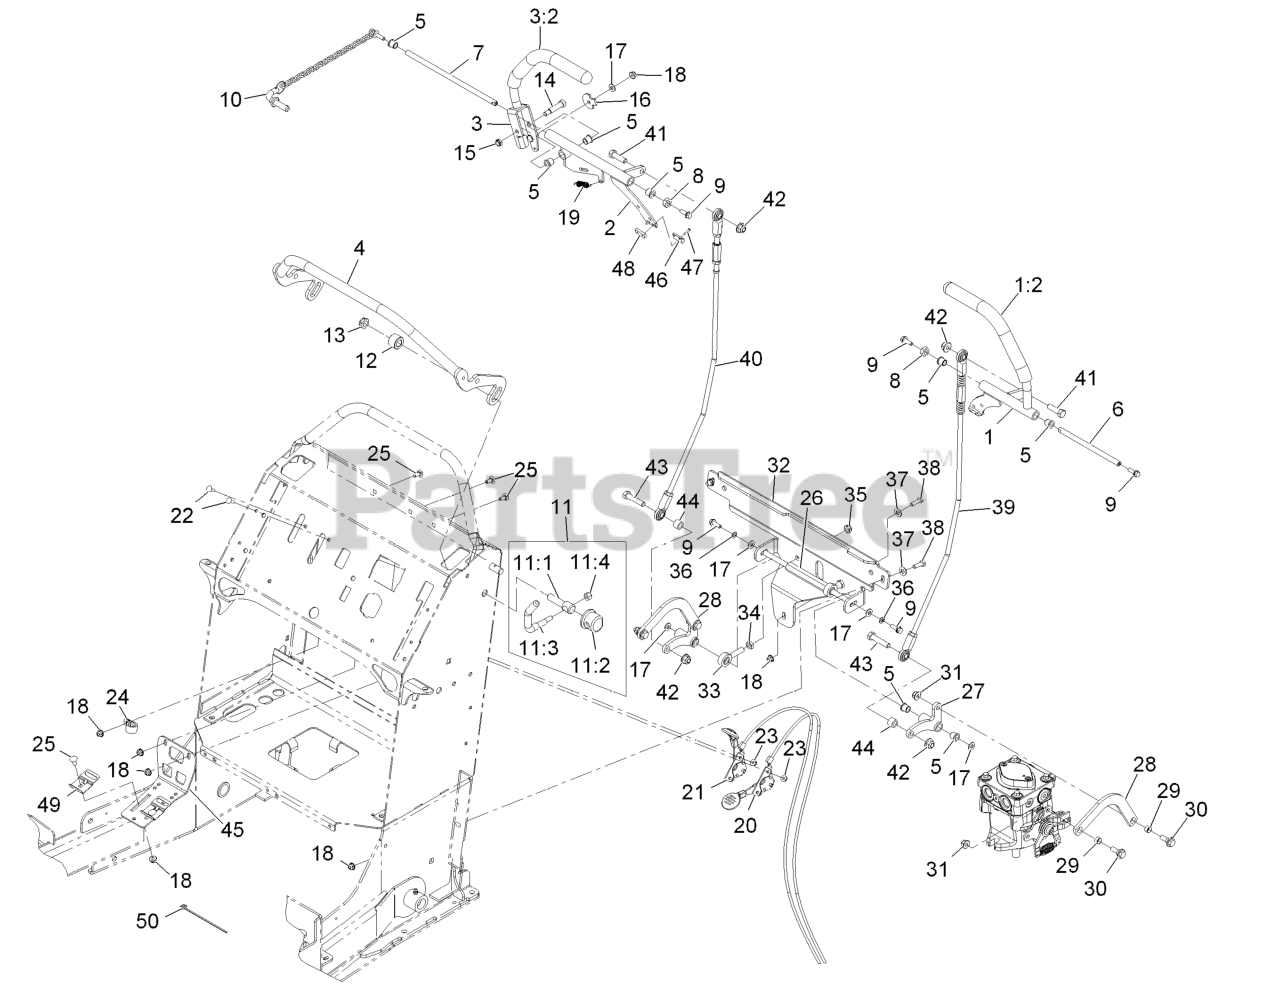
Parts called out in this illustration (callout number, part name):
1	LEVER ASM, LH
1:2	GRIP-HANDLE, CONTROL
2	MOTION CONTROL ASM-RH
3	LEVER ASM, RH
3:2	GRIP-HANDLE, CONTROL
5	BEARING
6	SHAFT-PIVOT, MOTION CONTROL
7	SHAFT-PIVOT, MOTION CONTROL
8	SPACER-SHAFT, DRIVE LEVER
9	SCREW-HHF
10	HOC PIN ASM
11	LEVER ASM
11:1	SCREW-LOCK
11:2	CAP-LOCK
11:4	NUT-LOCK, NI
12	SPACER-CLAMP
13	NUT-HEX
14	SCREW-HSH
15	NUT-LOCK, NI
16	CAM-LEVER
17	WASHER-FLAT
19	SPRING-EXTENSION
20	CONTROL-THROTTLE
21	CONTROL-CHOKE
22	BOLT-CARR
23	NUT-LOCK, FLANGE
24	CLAMP-CABLE
25	SCREW-CARR
26	SHAFT-BELLCRANK PIVOT
27	BELLCRANK-CONTROL, MOTION
28	LINK-BELLCRANK, PUMP
29	BUSHING-SLEEVE
30	SCREW-SHOULDER
31	NUT-HF, NI
32	BRACKET-BELLCRANK
33	BALLJOINT
34	NUT-HJ
35	NUT-HEX
36	SCREW-HH
37	WASHER-PLAIN
38	SCREW-HH
39	LINKAGE-TRACKING CONTROL,LH
40	LINKAGE-TRACKING CONTROL,RH
41	SCREW-HH
42	NUT-HF, NI
43	SCREW-HH
44	SPACER-WHEEL
45	BRACKET, REED SWITCH
46	ACTUATOR-SWITCH, REED
47	SCREW-HH
48	PLATE-TAPPED
49	CLAMP, REED SWITCH
50	TIE-CABLE
